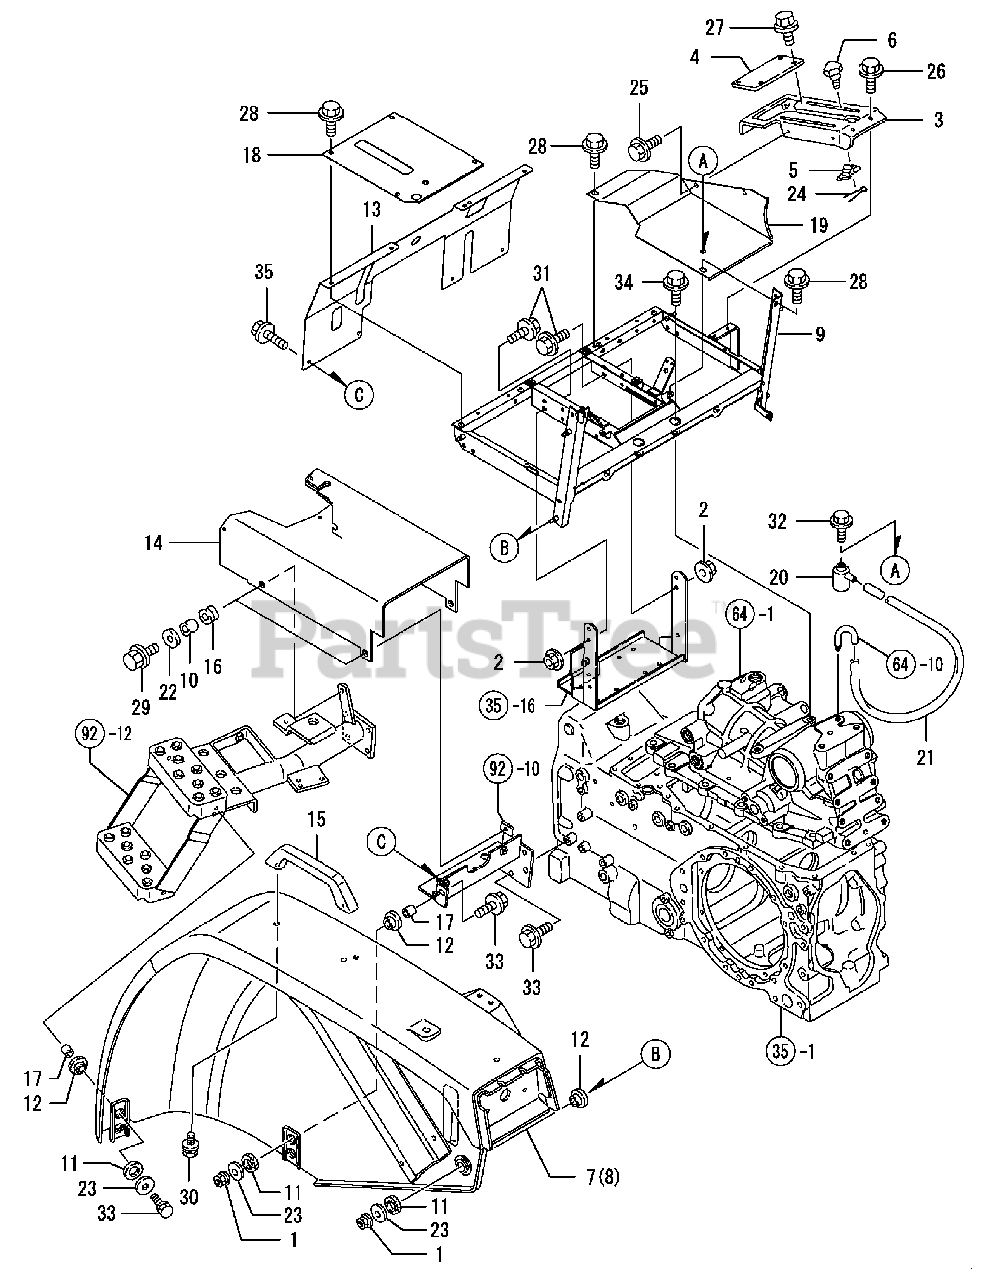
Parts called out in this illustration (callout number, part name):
1	NUT W/WASHER 8
2	NUT W/WASHER 8
3	GUIDE,LEVER HYD
4	COVER, LEVER GUIDE A
7	FENDER (M ASSY, L.H.
8	FENDER (M ASSY, L.H.
9	BRACKET, FENDER
11	CUSHION A, RUBBER
12	CUSHION B, RUBBER
13	COVER, HOUSING
14	COVER,CLUTCH(M CMP
17	COLLAR, CUSHION
19	COVER, DUST R.H.
21	PIPE, AIR BREATHER
24	COTTER PIN 2.0X16
25	BOLT M 6X 12 PLATED
26	BOLT M 6X 12 PLATED
27	BOLT M 6X 12 PLATED
28	BOLT M 6X 12 PLATED
29	BOLT M 6X 20 PLATED
30	BOLT M 8X 12 PLATED
31	BOLT M 8X 16 PLATED
32	BOLT M 8X 16 PLATED
33	BOLT M 8X 30 PLATED
34	BOLT M10X 25 PLATED
35	BOLT M 6X 12 PLATED
